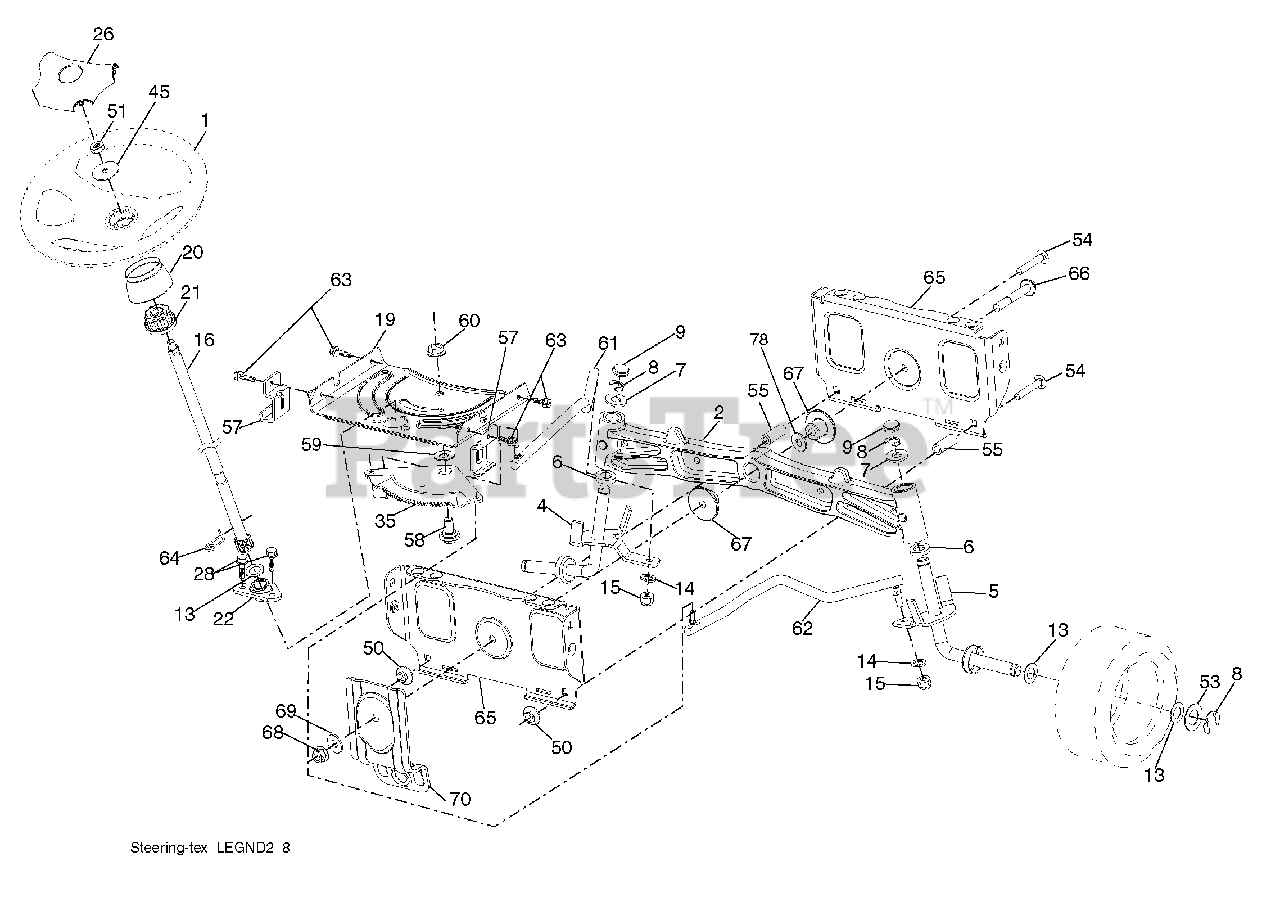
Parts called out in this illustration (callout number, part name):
1	Wheel, Steering
2	Axle Asm., Front
4	Spindle Asm., LH
5	Spindle Asm., RH
6	Bearing, Race Thrust Harden
7	Washer 25/32 x 1-5/8 x 16 Ga.
8	Ring, Klip #T5304-75
9	Cap, Spindle
13	Washer 25/32 x 1-1/4 x 16 Ga.
14	Washer, Lock Hvy Hlcl Spr 3/8
15	Nut, Crown Lock 3/8-24 unf
16	Shaft Steering
19	Plate Steering
20	Boot, Steering
21	Adapter, Wheel Steering
22	Bushing, Strg. Blk
26	Insert, Wheel Steering
28	Screw 3/8-16 x 3/4
35	Gear, Sector Plate
45	Washer 9/16 ID x 2-3/8 OD 12 GZIN
50	Nut Lock 3/8-16unc
51	Nut Hex Jam Toplock 1/2-20 unf
53	Washer Hardened .793 x 1.637 x .060
54	Bolt Hex 3/8-16 unc x 2-1/4
55	Spacer Brace Axle
57	Bracket Upstop
58	Bolt Shoulder Sector Pivot CFM
59	Washer Thrust Sector Steering
60	Nut Flange Lock 5/8-11
61	Draglink LH
62	Draglink, RH
63	Screw 5/16-18 x 3/4
64	Retainer Clip Spring Steering
65	Brace Axle Front
66	Bolt Hex Fghd 7/16-14 x 3 Serr
67	Bushing PM Front Axle
68	Nut Lock Flange 7/16-14 Gr. 5
69	Washer 1.5 x .505 x .118
70	Bracket Deck Susp. Front
78	Washer Thrust .515 x .750 x .033
